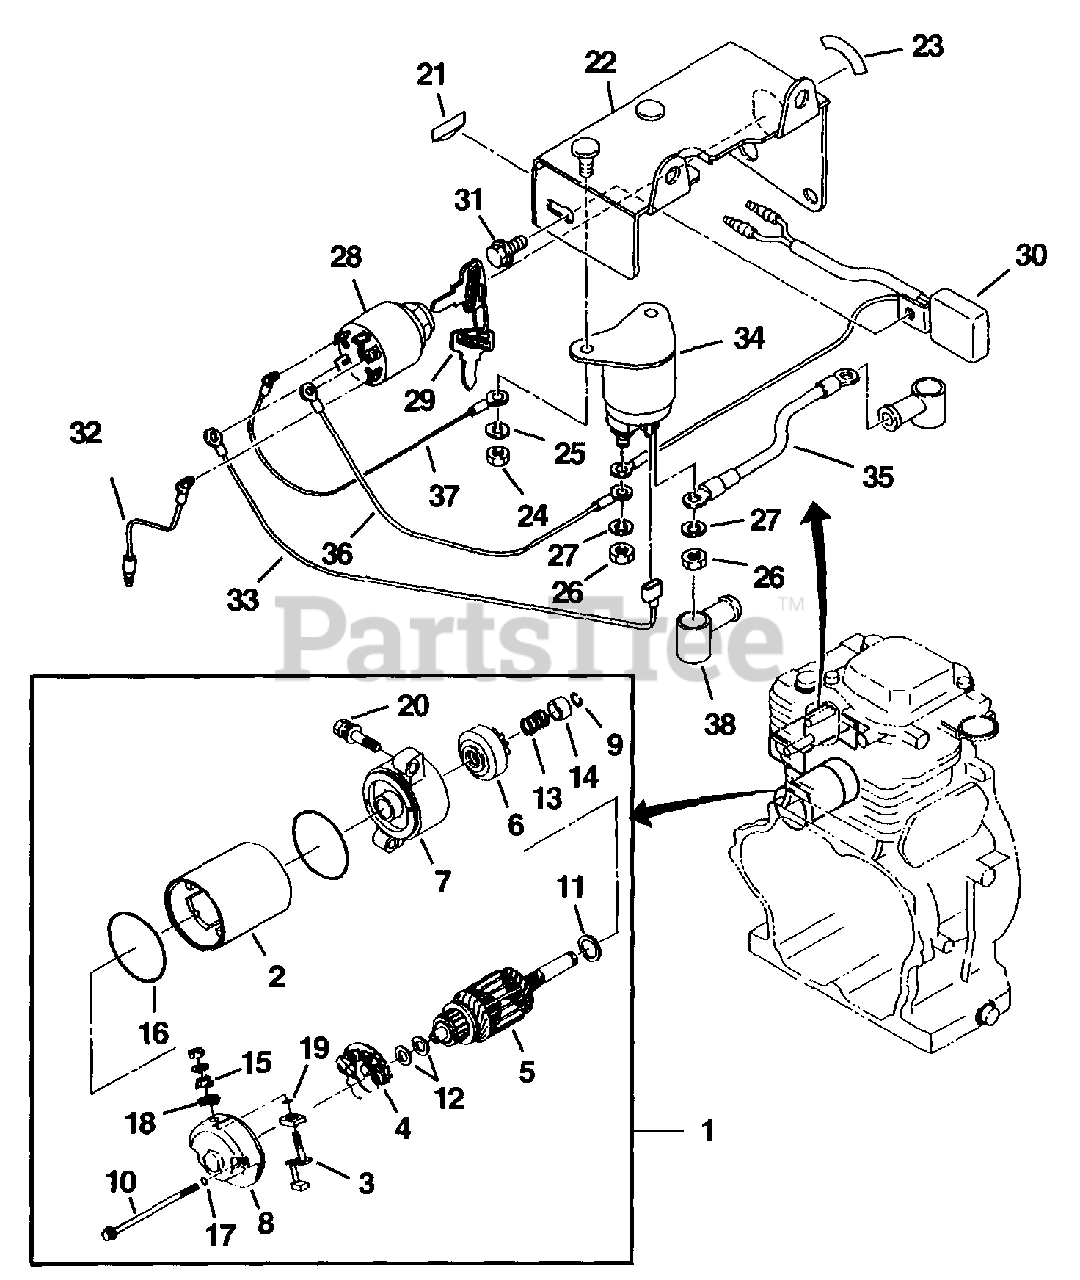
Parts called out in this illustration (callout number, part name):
1	Starting motor
3	Brush sub ay
4	Holder ay
5	Armature ay
6	Clutch sub ay
7	Housing ay
8	Frame ay
9	Snap ring
10	Through bolt
11	Plate washer
12	Plate washer
14	Pinion stop nut
20	Bolt & washer MS
21	Battery label
22	Control box
23	Starter switch label
25	Spring washer
27	Spring washer
30	Diode rectifier
31	Screw & washer
34	Magnetic switch
38	Wire casing
